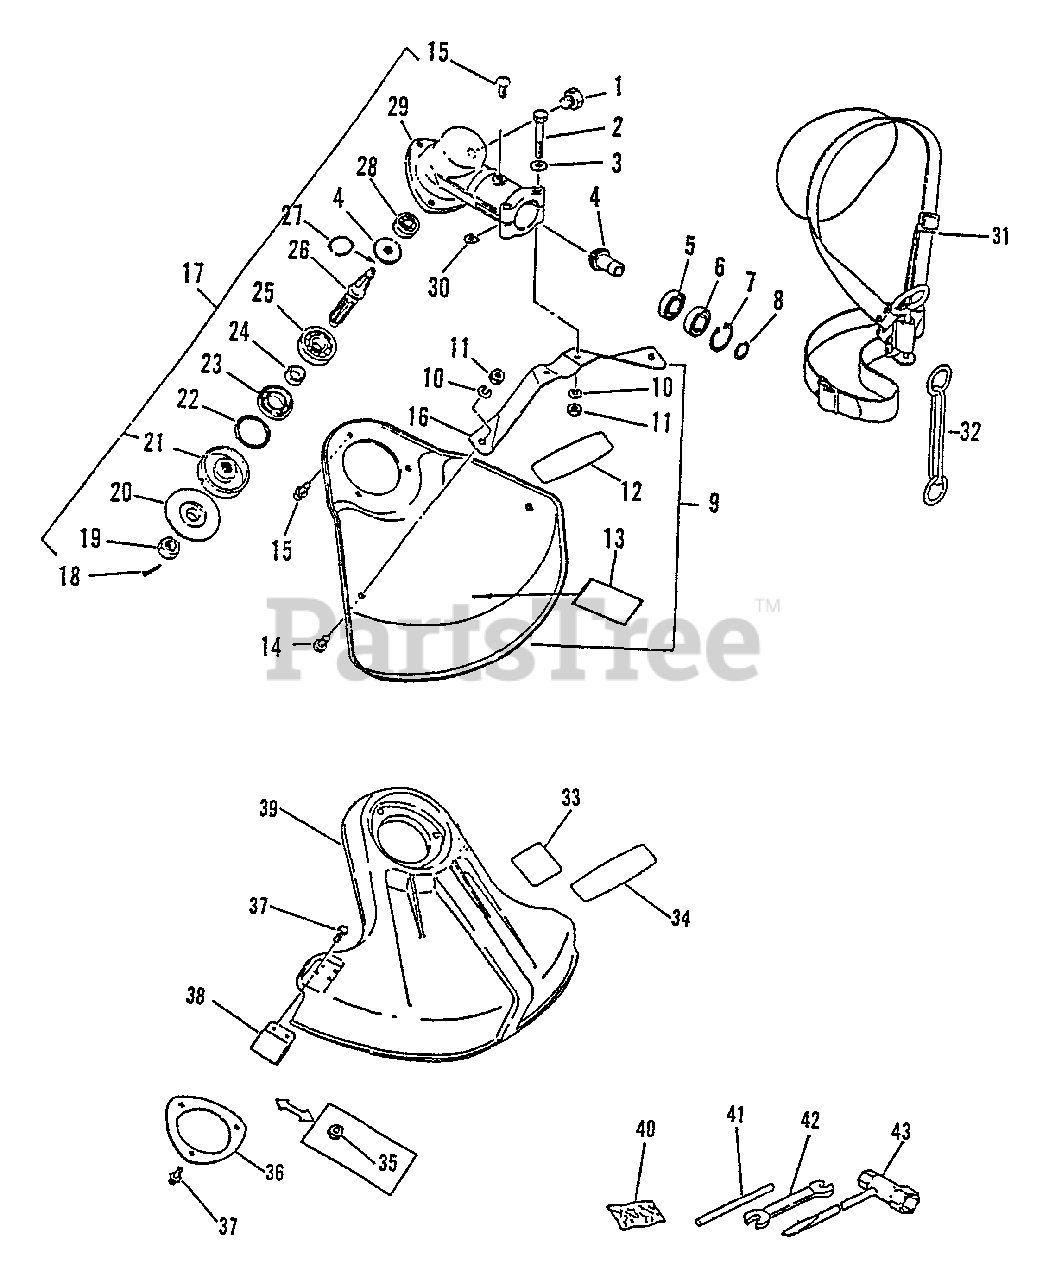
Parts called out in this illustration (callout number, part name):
1	BOLT - 8X8
2	BOLT - 5X35
3	WASHER - 5
4	GEAR SET - BEVEL
5	BEARING, BALL - 6900
6	BEARING, BALL - 6900Z
7	RING, RETAINING - 22
8	RING, RETAINING - 12
9	DEBRIS SHIELD KIT - METAL
10	LOCKWASHER - 5
12	LABEL - ECHO
13	LABEL - CAUTION
14	SCREW - 5X8
15	SCREW - 5X10
16	BRACKET, SHIELD
17	GEAR CASE ASSY
18	PIN, SPLIT - 2X22
19	NUT - 10 -- LEFT HAND
20	ADAPTOR, BLADE - LOWER
21	ADAPTOR, BLADE - UPPER
22	RING, RETAINING - 32
23	SEAL, OIL
25	BEARING, BALL - 6201
26	GEAR - SHAFT
27	RING, RETAINING - 10
28	BEARING, BALL - 609
29	CASE, GEAR
31	SHOULDER STRAP ASSY
33	LABEL - CAUTION
34	LABEL - ECHO
36	PLATE, SHIELD
37	SCREW - 5X16
38	KNIFE, TRIMMER LINE
39	DEBRIS SHIELD KIT
40	PIN, SPLIT - 2X22
41	LOCKING TOOL
42	SPANNER - 8X10mm
43	T-WRENCH - 17X19mm
